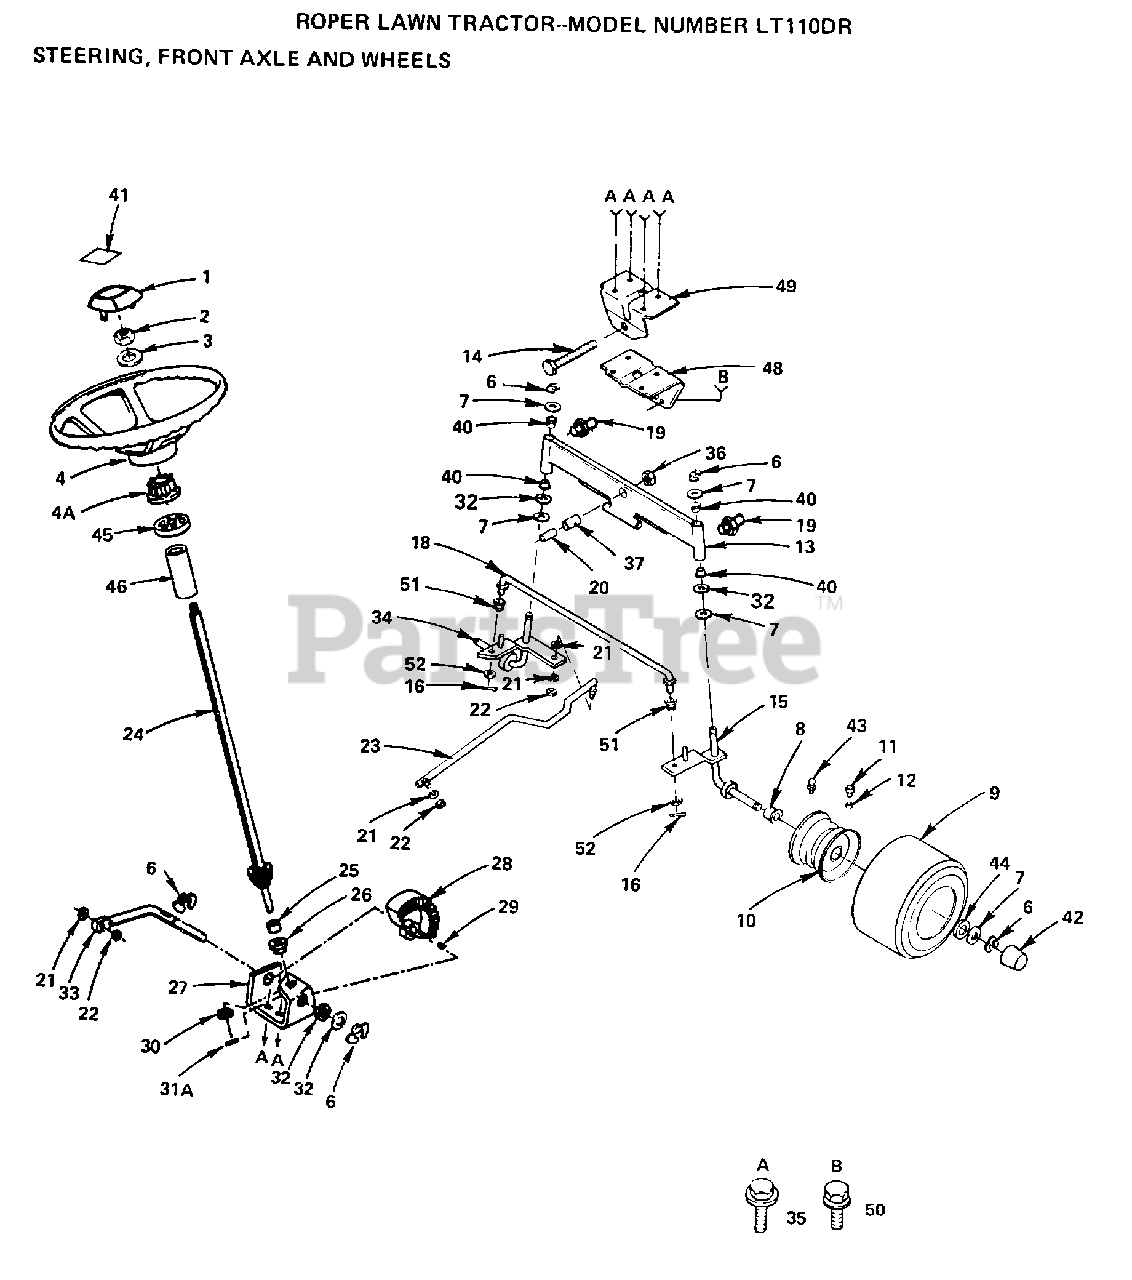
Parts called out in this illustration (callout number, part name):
1	INSERT-WHEEL LT
2	NUT
3	WASHER
4A	ADAPTER LT
6	RING
8	"FLANGE, BEARING"
11	VALVE STEM LT
12	VALVE CAP
13	FRONT AXLE
14	BOLT LT
16	COTTER PIN
19	ZERK M
21	LOCKWASHER
23	LINK-DRAG LT
24	SHAFT ASSY LT
25	SHAFT SPACER LT
26	BUSHING
28	GEAR-SECTOR T
29	KEY-WOODRUFF LT
30	WASHER D
32	WASHER .T
33	ROD-STEERING T
34	SPINDLE-LH LT
35	SCREW
36	"NUT-LOC,FLANGE LT"
40	COL. SRTG. BEAR.
41	DECAL - STEERING WHEEL
42	HUB CAP
43	FITTING LT
48	SUPPORT.SADDLE.FT
49	SUPPORT-SADDL T
50	SCREW LT
52	WASHER
